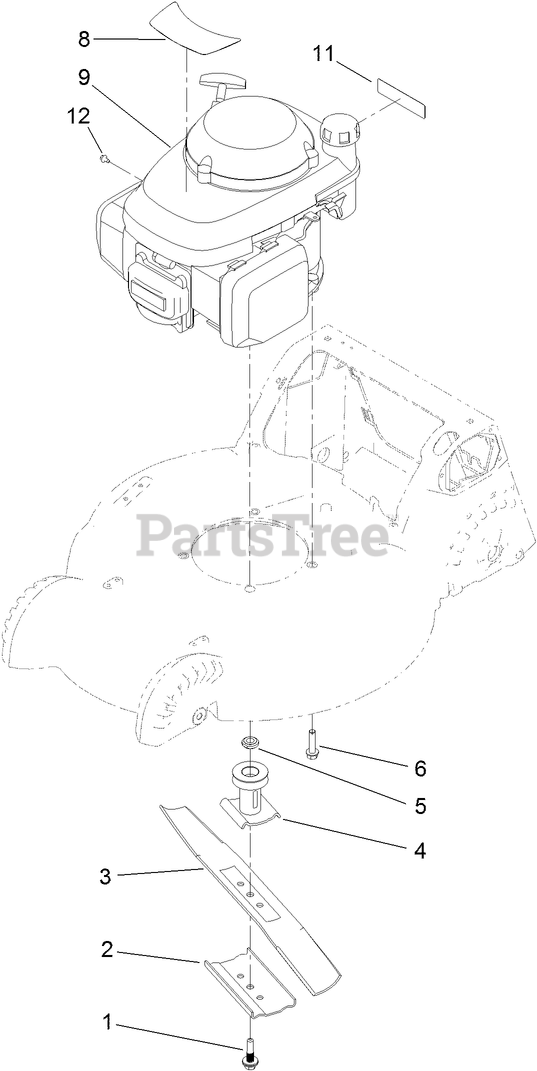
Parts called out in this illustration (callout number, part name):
1	BOLT-BLADE
2	SUPPORT-BLADE
3	BLADE-BAGGING
4	DRIVER-BLADE
5	Spacer-Driver
6	SCREW-HWH
8	DECAL-ENGINE
11	DECAL-ARRESTER, SPARK
12	SCREW-HWH
